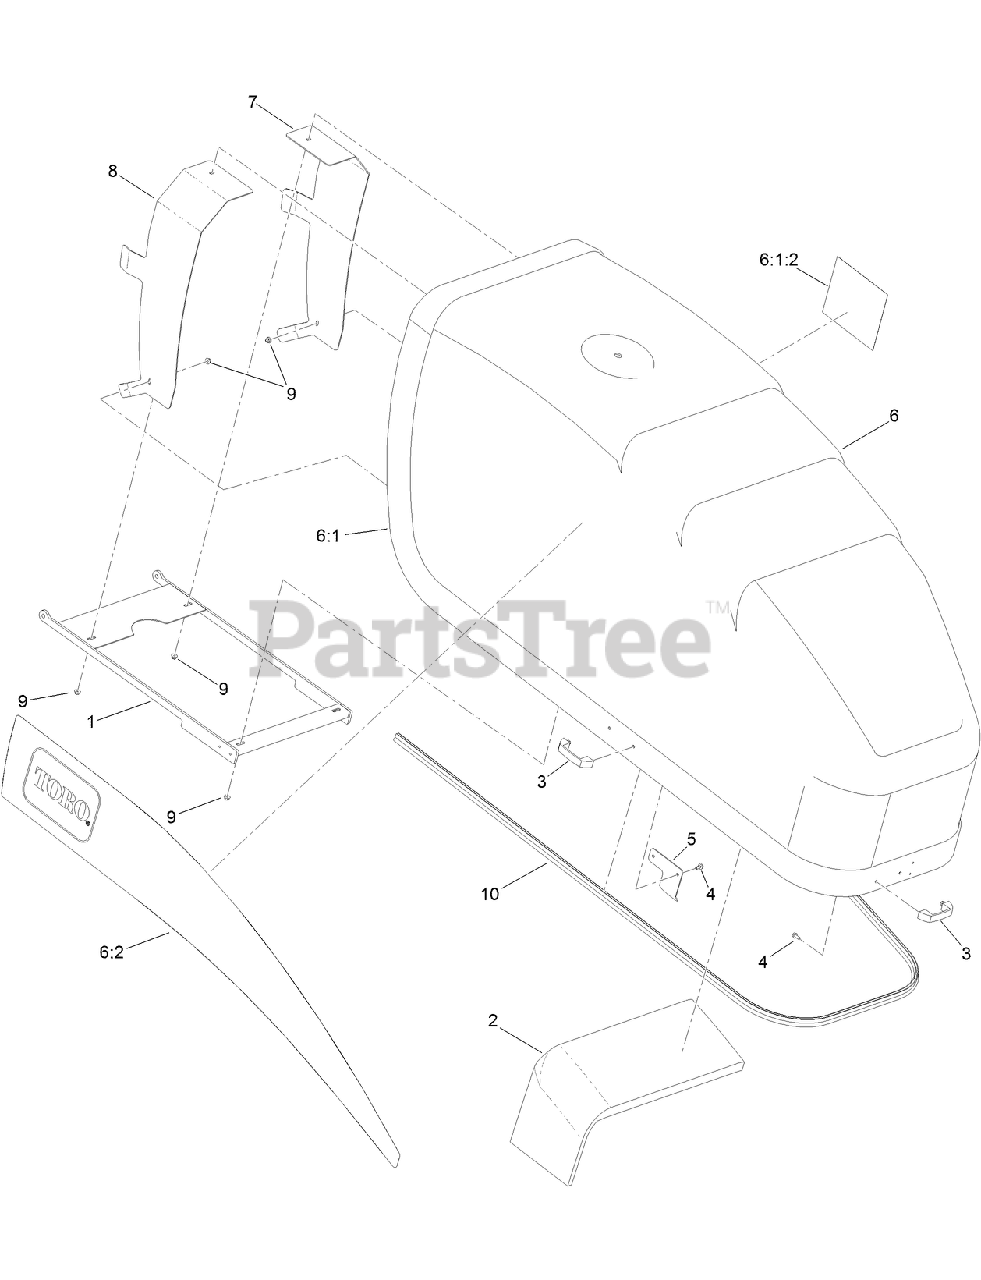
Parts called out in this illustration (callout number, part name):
1	HINGE-HOOD, FRONT
2	FOAM-HOOD, REFLECTIVE
3	HANDLE-GRAB
4	SCREW-HHF
5	GUIDE-HOOD, FRONT
6	FRONT HOOD AND DECAL ASM
6:1	HOOD-FRONT
6:1:2	SCREEN-HOOD, FRONT
6:2	DECAL-DD 4050
7	PLATE-CATCH, HOOD
8	PLATE-CATCH, HOOD
9	NUT-HF, NI
10	SEAL-BULB
